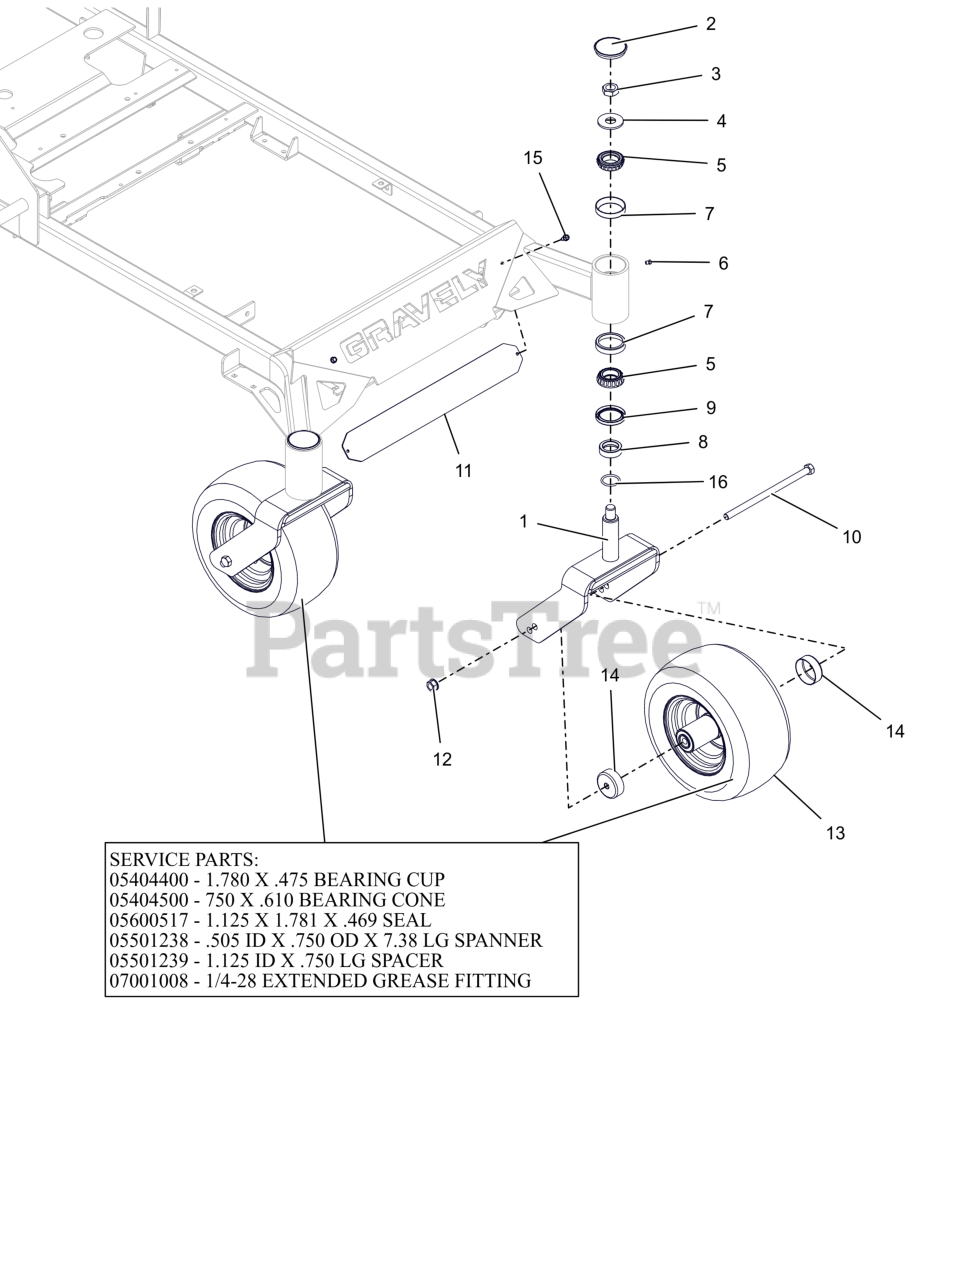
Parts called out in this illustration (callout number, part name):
1	CASTER FORK WMT - RED
2	CAP, DUST
3	NUT, JAM-TOPLOCK .750-16 ZCC
4	WSHR-FL-STL 0.812X2X0.148 ZCC
5	BRG-CONE 1.25X.66
6	FTG, .25-28 FLUSH MNT GREASE
7	BRG-CUP 2.328X.465
8	SPCR, FRONT CASTER FORK
9	SEAL, OIL 1.75 X 2.332 X .312
10	BLT, HEX .50-13X9.00 G5 ZCC
11	BUMPER LOGO BACKING PLATE -BLK
12	NUT-LK-TOP-FLG .500-13 GF ZCC
13	ASM, WHL/TIRE 13X6.50-6 SEMI
13	BRG-CUP 1.781X.475
13	BRG-CONE .750X.61
13	SEAL, 1.125 X 1.781 X .469
13	SPANNER,.505ID X.750OD X7.38LG
13	SPACER, 1.125 ID X .750 LG
13	GREASE FITTING 1/4-28 EXTENDED
14	SHIELD, WHEEL BEARING
15	SCR-TAP .25-20X.50 HWH ZCC
